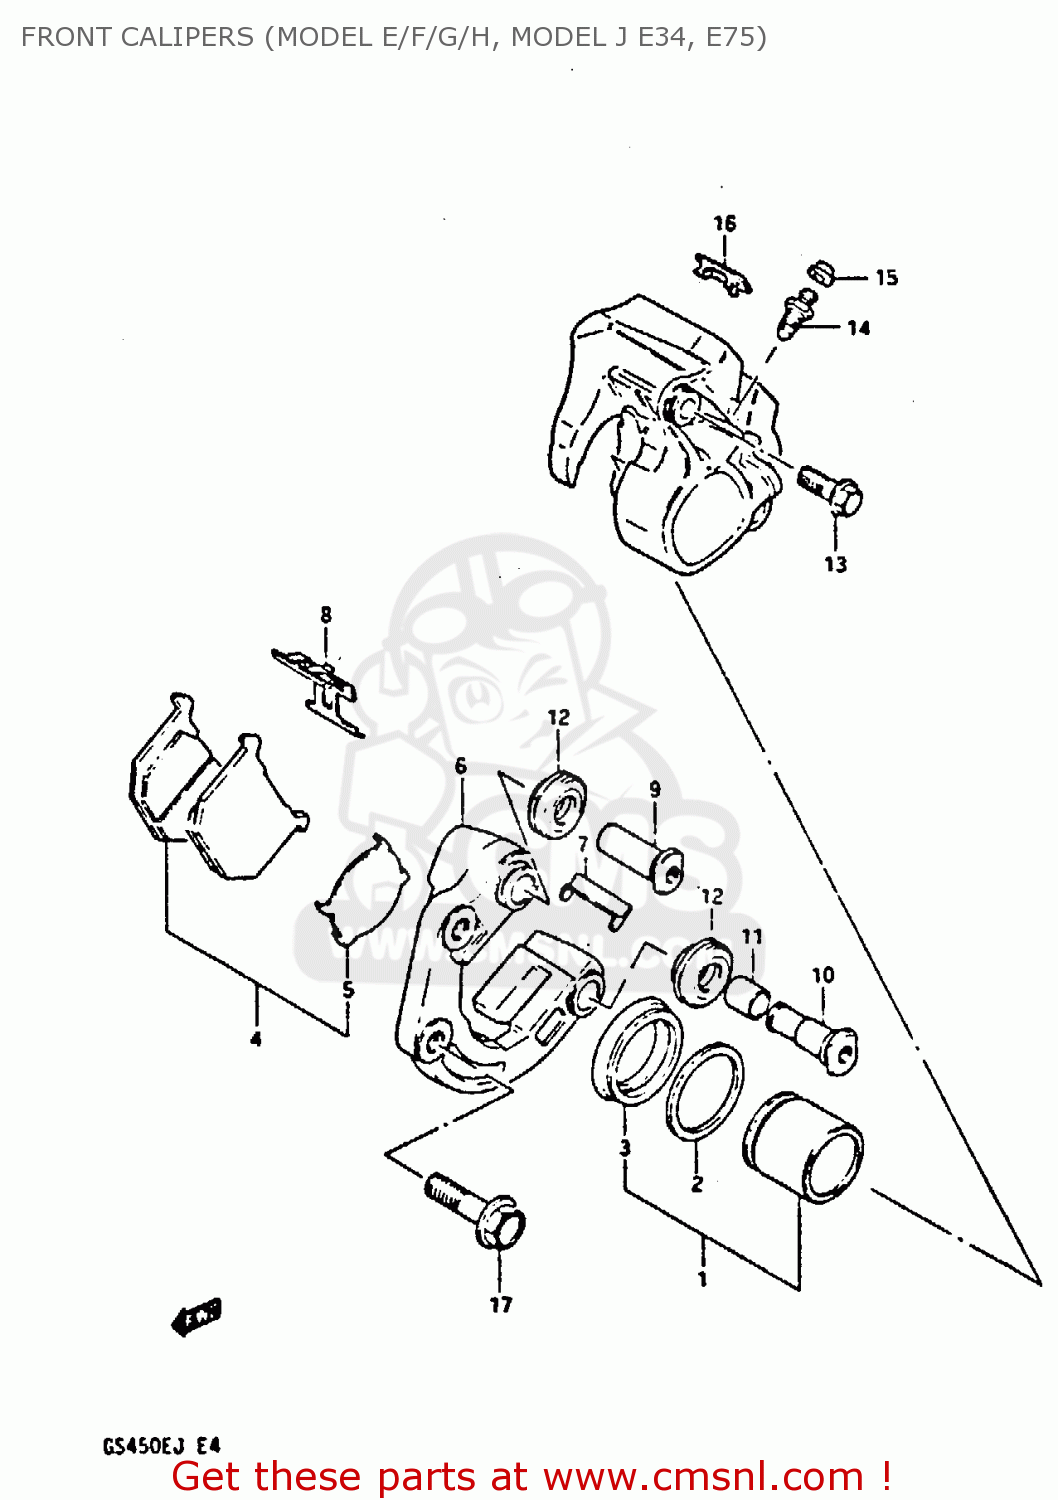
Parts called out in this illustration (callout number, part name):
1	PISTON SET
2	SEAL,FR CALIPE
3	BOOT,PISTON
4	PAD SET,BRAKE (MCA)
5	SHIM,PAD
6	CARRIER,CALIPER,LEFT
7	GUIDE,PAD
8	SPRING,PAD
9	AXLE NO.1
10	AXLE NO.2
11	BUSH,AXLE
12	BOOT,AXLE
13	BOLT
14	BLEEDER
15	CAP,BREATHER
16	COVER
17	BOLT 10X37
